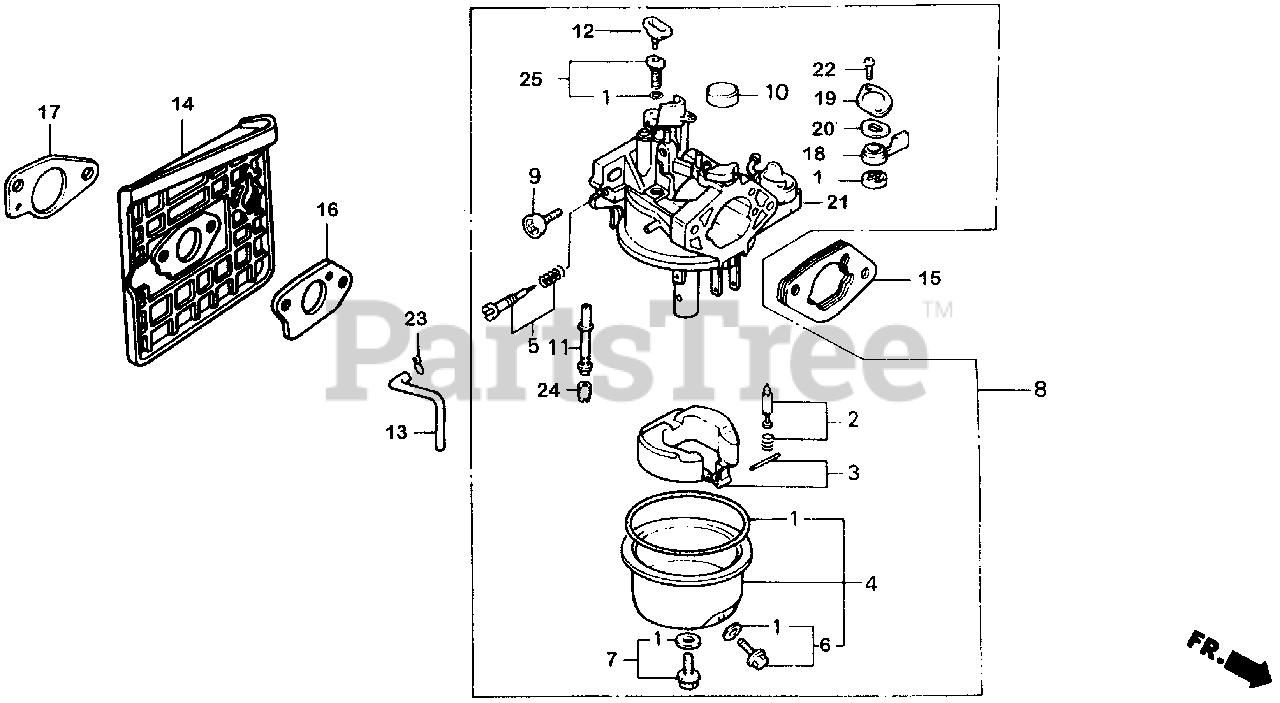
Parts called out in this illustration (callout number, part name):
1	GASKET SET (EXC. 16173-001-004) (EXCEPT 16173-001-004)
2	VALVE SET, FLOAT
4	CHAMBER SET, FLOAT
5	SCREW SET, PILOT
6	SCREW SET, DRAIN
7	SCREW SET
8	CARBURETOR ASSY. (BE86C A)
9	SCREW, THROTTLE STOP
10	CAP, CHOKE DUST
11	NOZZLE, MAIN
12	COLLAR, SETTING
13	TUBE, AIR VENT (75MM)
14	INSULATOR, CARBURETOR
15	SPACER, CARBURETOR
16	GASKET, CARBURETOR
17	GASKET, INSULATOR
18	LEVER, PETCOCK
19	PLATE, LEVER SETTING
20	SPRING, PETCOCK LEVER
21	GASKET, PETCOCK
22	SCREW, PAN (3X8)
23	CLIP, TUBE (B8)
24	JET, MAIN (#88)
24	JET, MAIN (#92)
24	JET, MAIN (#90)
25	JET SET, PILOT (#40)
NI	ANTI-ICING KIT
